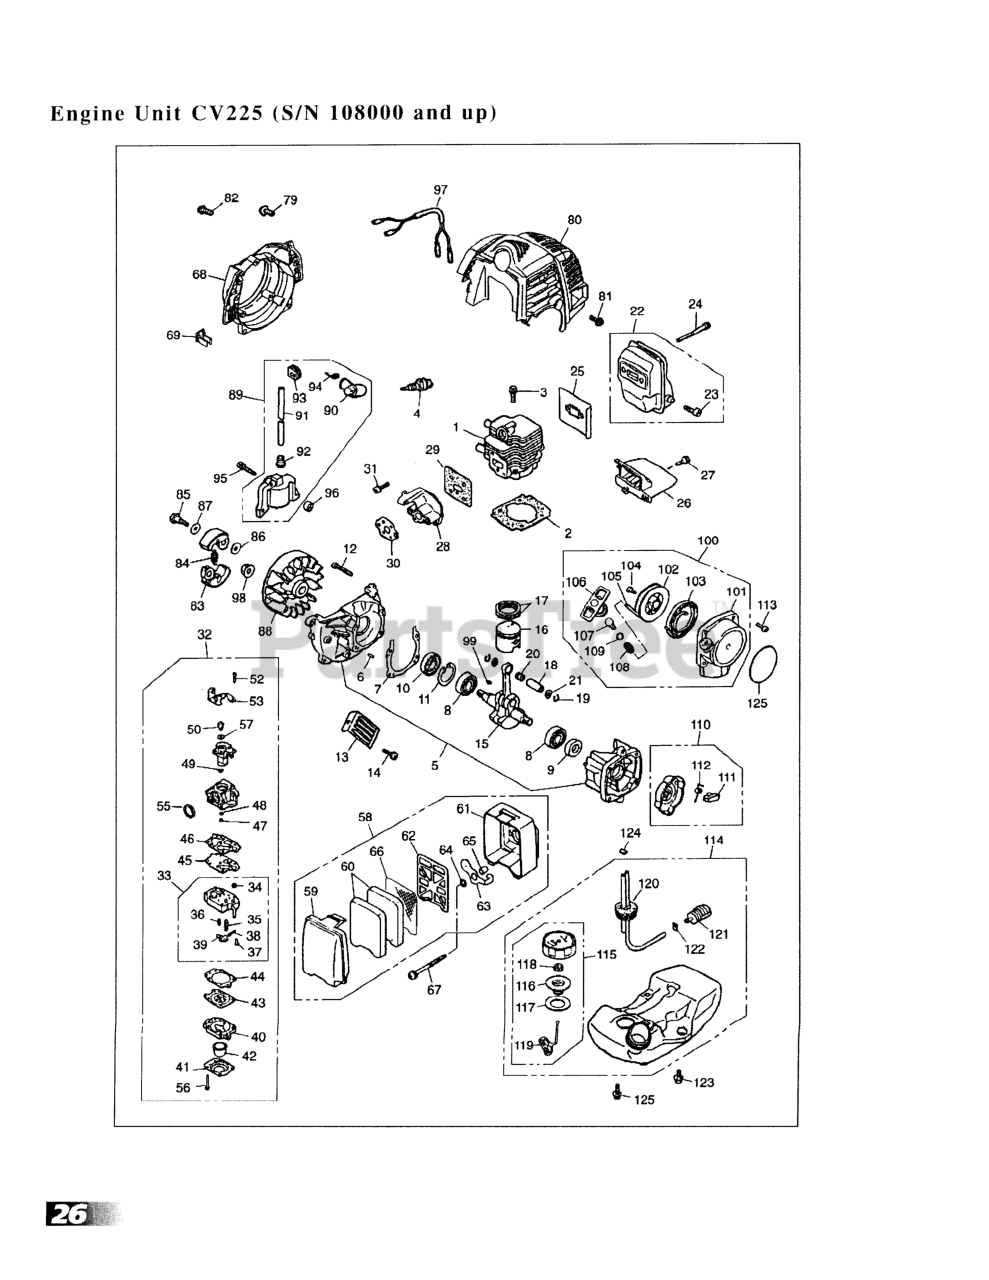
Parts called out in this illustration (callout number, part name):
1	CYLINDER
2	GASKET, BASE (RPLS -12212)
3	BOLT, M5 X 22
5	CRANKCASE
6	PIN
7	GASKET (RPLS -21140)
8	BEARING
9	SEAL, OIL (RPLS 1100-21210)
10	SEAL, OIL (RPLS 1140-21220)
11	RING, SNAP, M28 x 1.2
12	BOLT, M5 X 30
14	SCREW,M5 X 14 (RPLS 1400-15510
15	CRANKSHAFT (RPLS 1850-42000)
16	PISTON (REPLACES 1140-41110)
17	RING, PISTON (RPLS 1850-41210)
18	PIN, PISTON 5x8x26
19	RING, SNAP (RPLS 1101-41320)
20	BEARING (RPLS 1140-41330)
21	WASHER
22	MUFFER ASSEMBLY
23	ARRESTER (RPLS 5850-15140)
24	BOLT, M5 x 50
25	GASKET
26	PLATE, MUFFLER (RPLS -15220)
27	SCREW, M4 X 16
28	INSULATOR
29	GASKET (RPLS -13120)
30	GASKET (REPLACES -13130)
31	SCREW, M5X20 (RPLS.1400-75510)
32	CARBURETOR ASSY.
33	BODY, PUMP
35	VALVE, INLET
36	SPRING, METERING LEVER
37	SCREW, METERING LEVER PIN
38	PIN, METERING LEVER
39	LEVER
40	BODY, PURGE
41	COVER, PUMP
42	PUMP, PRIMING
43	DIAPHRAGM (USE 4810-81260)
44	GASKET, DIAPHRAGM
45	DIAPHRAGM
46	GASKET, PUMP
47	JET
48	RING, O
49	RING
50	SWIVEL
52	SCREW
55	RING, PACKING
56	SCREW
57	WASHER
58	CLEANER ASSY (RPLS -82000)
59	COVER
60	FILTER
61	HOUSING
62	PLATE
64	WASHER
65	SLEEVE (REPLACES 1750-82060)
66	SCREEN
67	SCREW, M5 x 60
68	COVER, FAN
69	CLAMP
79	SCREW, M5X20 (RPLS.1400-75510)
80	COVER, ENGINE (USE -32111)
81	SCREW (RPLS-32161)
82	SCREW, M5 X 10
83	SHOE
84	SPRING
85	BOLT
86	WASHER, FLAT (USE 182303)
88	ROTOR
89	COIL-A (REPLACES -71200)
90	CAP
91	CORD
92	CAP
93	GROMMET
94	SPRING
95	BOLT
96	SPACER
97	CORD COMP
99	KEY
100	RECOIL ASSEMBLY
101	CASE
102	REEL
103	SPRING, SPIRAL
104	SCREW (RPLS -75150)
105	ROPE
106	KNOB
107	COLLAR
108	SPRING
109	WASHER
110	PULLEY ASSY (RPLS -75210)
111	RATCHET (RPLS 1850-75220)
112	SPRING, RETURN
113	SCREW (RPLS-32161)
114	TANK ASSY (RPLS -85000)
115	CAP ASSY (RPLS. 5601-85201)
116	HOLDER - A (RPLS 5601-85230)
117	PACKING
118	FILTER
119	STOPPER
120	PIPE COMPLETE
121	FILTER (RPLS 1850-85300)
122	CLIP (REPLACES 2841-31280)
123	SCREW W/ WASHER
124	CLIP
125	SCREW
126	LABEL
